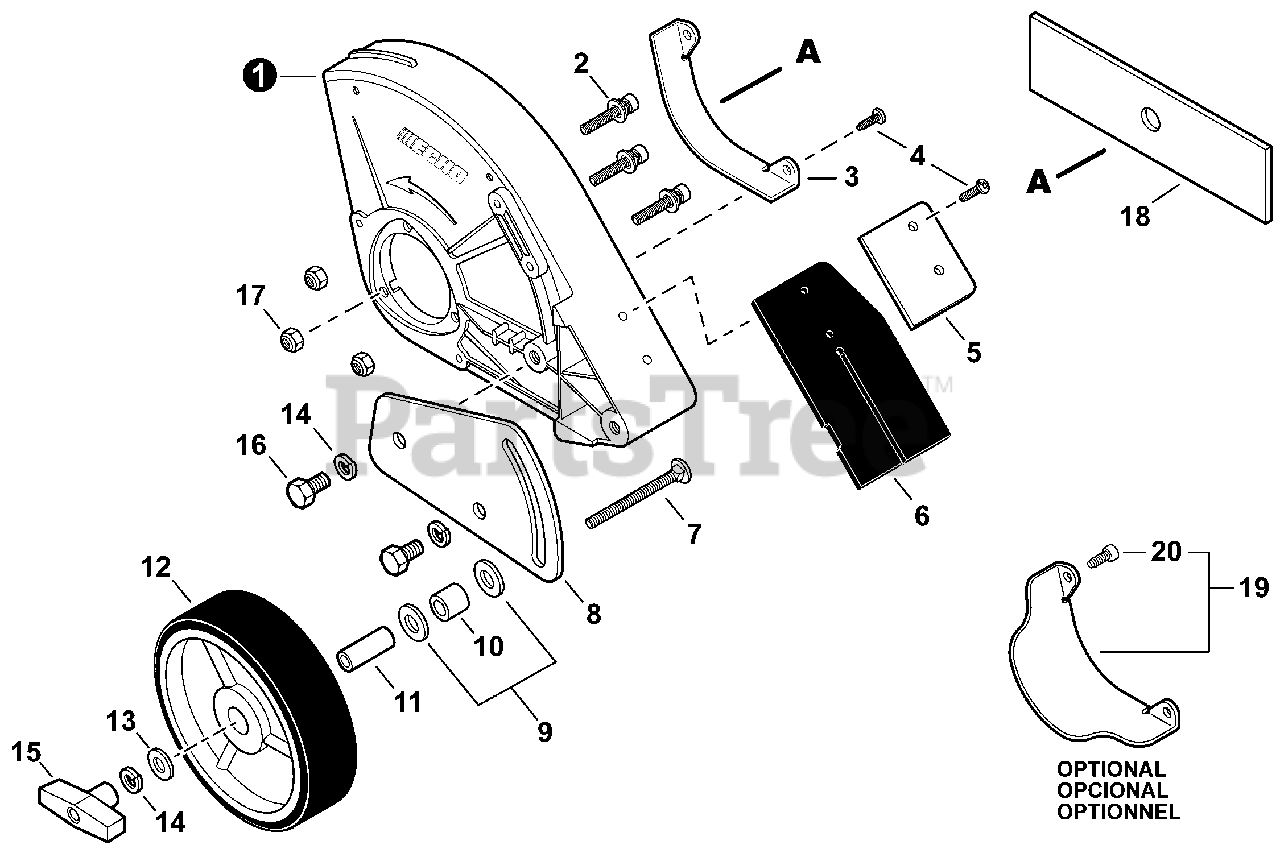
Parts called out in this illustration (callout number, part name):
1	SHIELD, BLADE
2	BOLT 5×25
3	GUARD, SHIELD
4	SCREW 4×12
5	PLATE, FLAP
6	FLAP, DEBRIS
7	BOLT 5/16"-18×3"
8	BRACKET, WHEEL
9	WASHER 10
10	COLLAR 8
11	COLLAR 12
12	WHEEL
13	WASHER 8
14	WASHER, SPRING 8
15	KNOB, FASTENER
16	BOLT 8×14
17	NUT, LOCK M5
18	BLADE - 2 PK
19	GUARD KIT, SHIELD
20	BOLT, TORX 4×12
